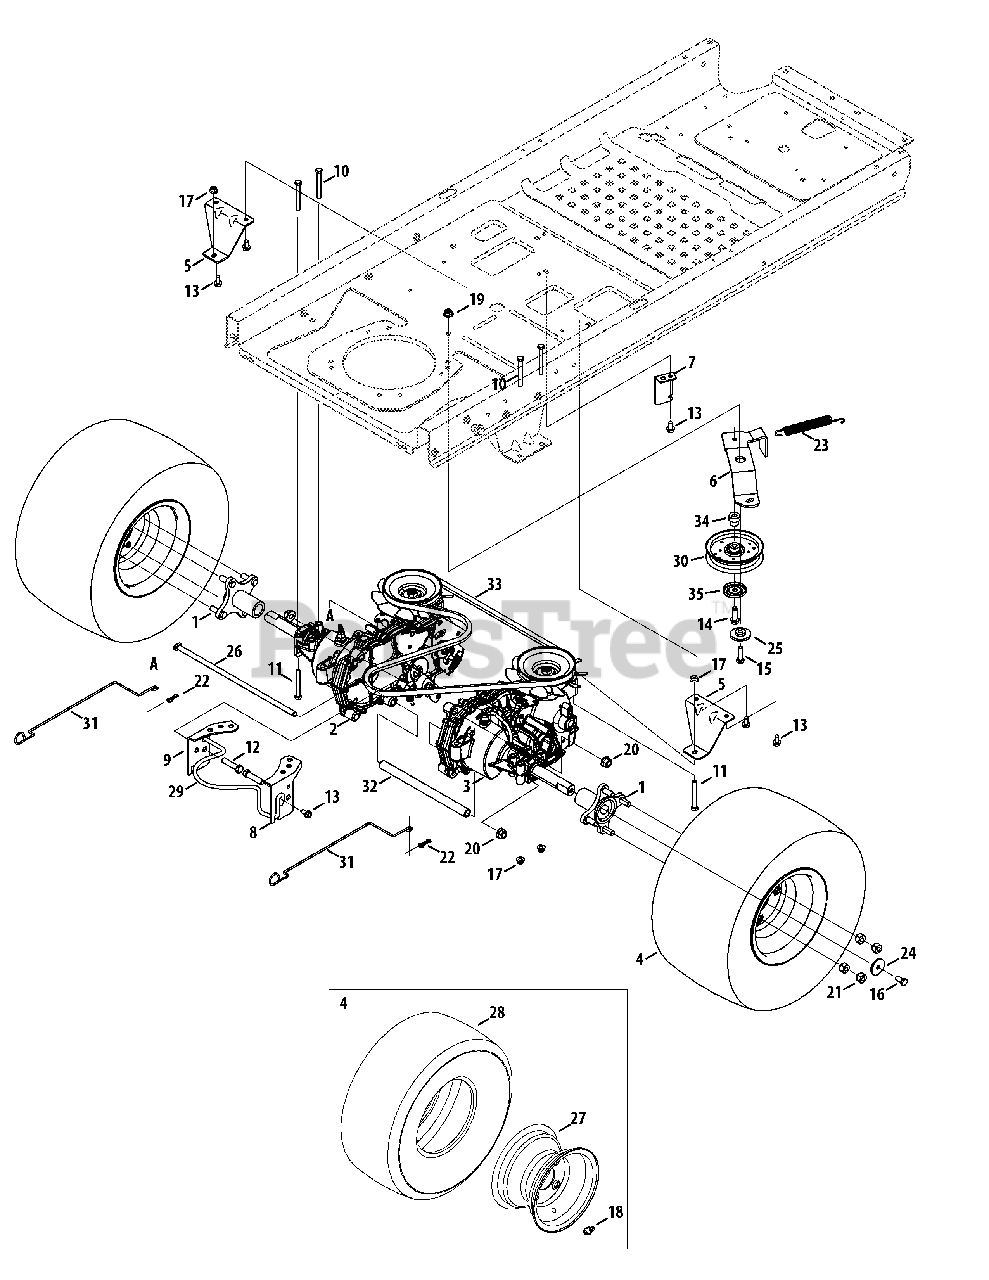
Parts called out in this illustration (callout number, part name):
1	Wheel Hub Assembly
2	Transmission Assembly, LH
3	Transmission Assembly, RH
4	Complete Wheel, 18 x 8.5-8
5	Transmission Mounting Bracket
6	Idler Bracket
7	Spring Mounting Bracket
8	Transmission Bracket
9	Transmission Bracket
10	Hex Screw, 5/16-18 x 2.75
11	Screw-HHCS 5/16-18 x 2.25
12	Hex Screw, 7/16-20 x 1.75
13	Hex Washer Screw, 5/16-18 x .750
14	Hex Washer Screw, 3/8-16 x 1.250
15	Hex Screw, 3/8-16 x 1.00
16	Hex Screw, 3/8-16 x .75
17	Flange Lock Nut, 5/16-18
18	Valve Tubeless
19	Jam Lock Nut, 3/8-16
20	Flange Lock Nut, 7/16-20
21	Lug Nut, 7/16-14
22	Bow-Tie Cotter Pin
23	Extension Spring, .75 Dia. x 6.02
24	Flat Washer, .390 x 1.50 x .134
25	Shoulder Spacer, .884 x .190
26	Rod, .405 Dia. x 14.0 LG
28	Tire Only, 18 x 8.5-8
29	Engine Keeper Rod
30	Idler Pulley, 4.25 Dia.
31	Bypass Rod
32	Tube, .51 ID x .75 OD x 10.2
33	Belt, A-Type x 67.0
34	Shoulder Spacer
35	Pulley Cap
